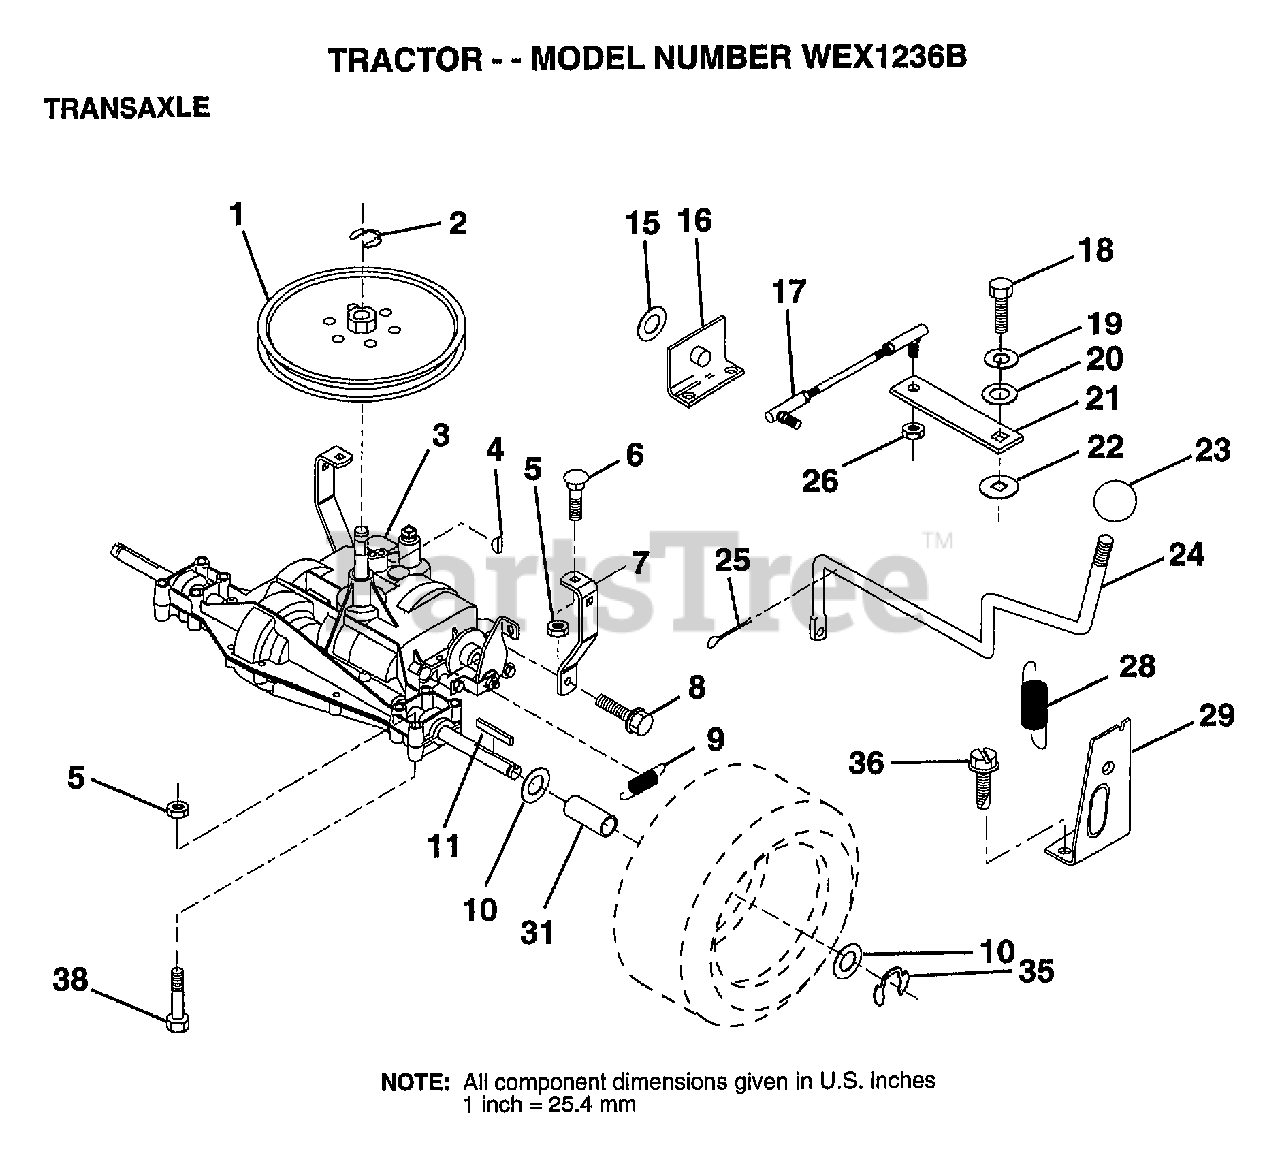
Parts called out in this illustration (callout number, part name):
1	PULLEY
6	BOLT
7	"STRAP,TORQUE"
8	SCREW
9	SPRING.BRAKE.RETU
10	WASHER
11	SQUARE KEY
16	SUPPORT HANDLE SHIFT LH
17	LINK SHIFT
18	BOLT.1/4-28.W/PAT
19	LOCKWASHER
20	WASHER LT
22	WASH-SHFT PLT LT
23	KNOB T (1/2-HOLE)
24	"ROD,SHIFT"
25	PIN COTTER 1/8
26	NUT.LOCK.5/16-24
28	"SPRING,EXT"
29	"SUPT,HDLE RH"
31	SPACER AXLE
35	E-RING LT
36	SCREW
38	BOLT.HEX.FLGHD
